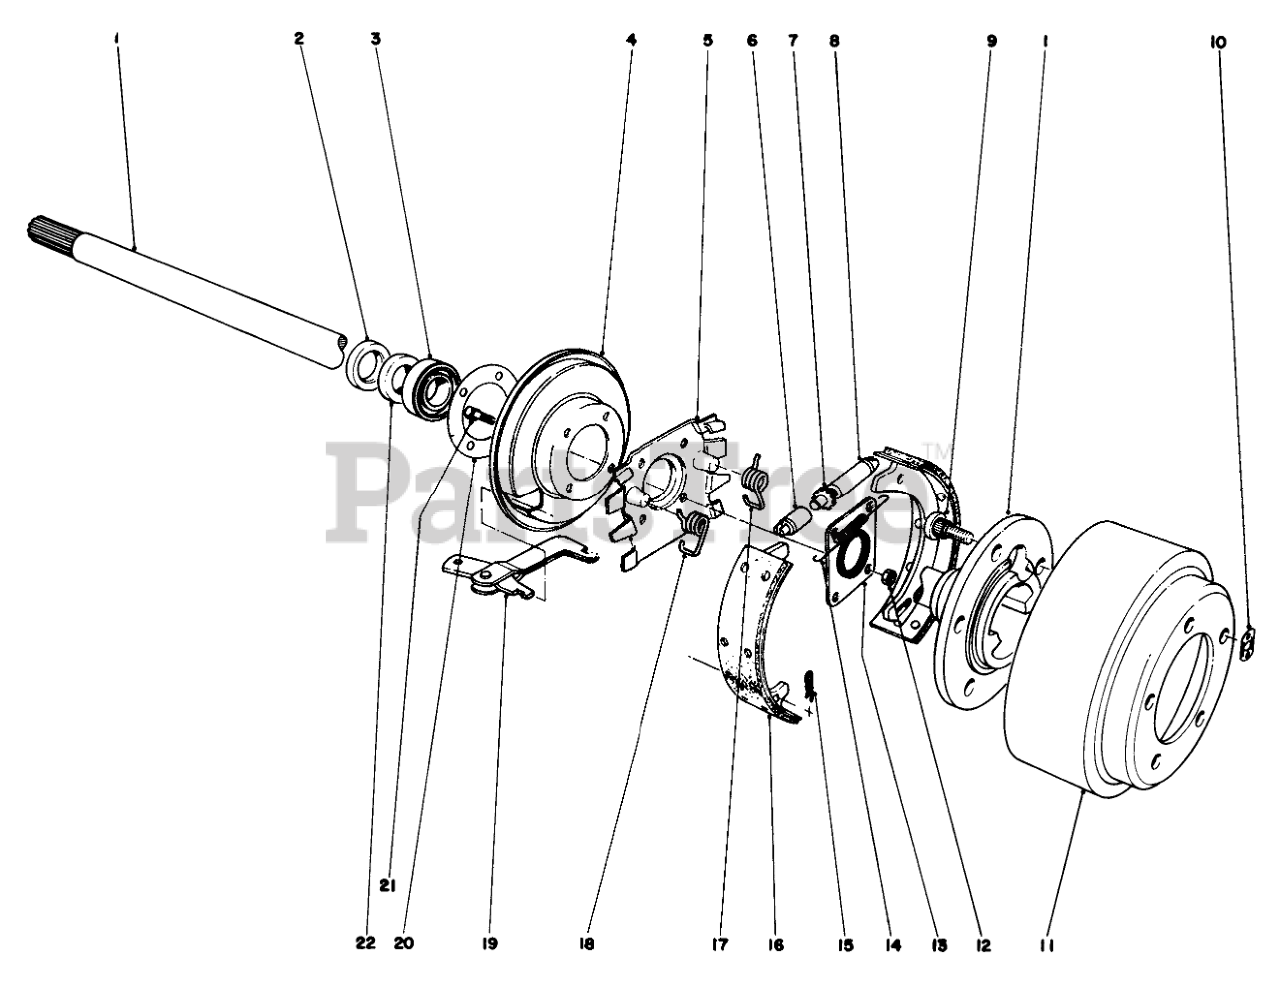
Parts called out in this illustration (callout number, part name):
1	AXLE SHAFT L.H.
2	Oil Seal
3	BEARING ASM
4	SHIELD-DUST
5	Torque Spider
6	SOCKET-SCREW, ADJUSTING
7	SCREW-ADJUSTING
8	NUT-PIVOT
9	STUD-DRIVE
10	CLIP-RETAINING
11	DRUM-BRAKE
12	Locknut
13	SEAL-GREASE
14	SPRING-SCREW, ADJUSTING
15	RETAINER-LEVER, BRAKE
16	Assy.-Shoe & Lining
17	SPRING-RETURN, LH
18	SPRING-RETURN, RH
19	BRAKE LEVER ASSY
20	Gasket Wheel Baaring
21	Screw
22	RING-RETAINING, WHEEL BEARING
